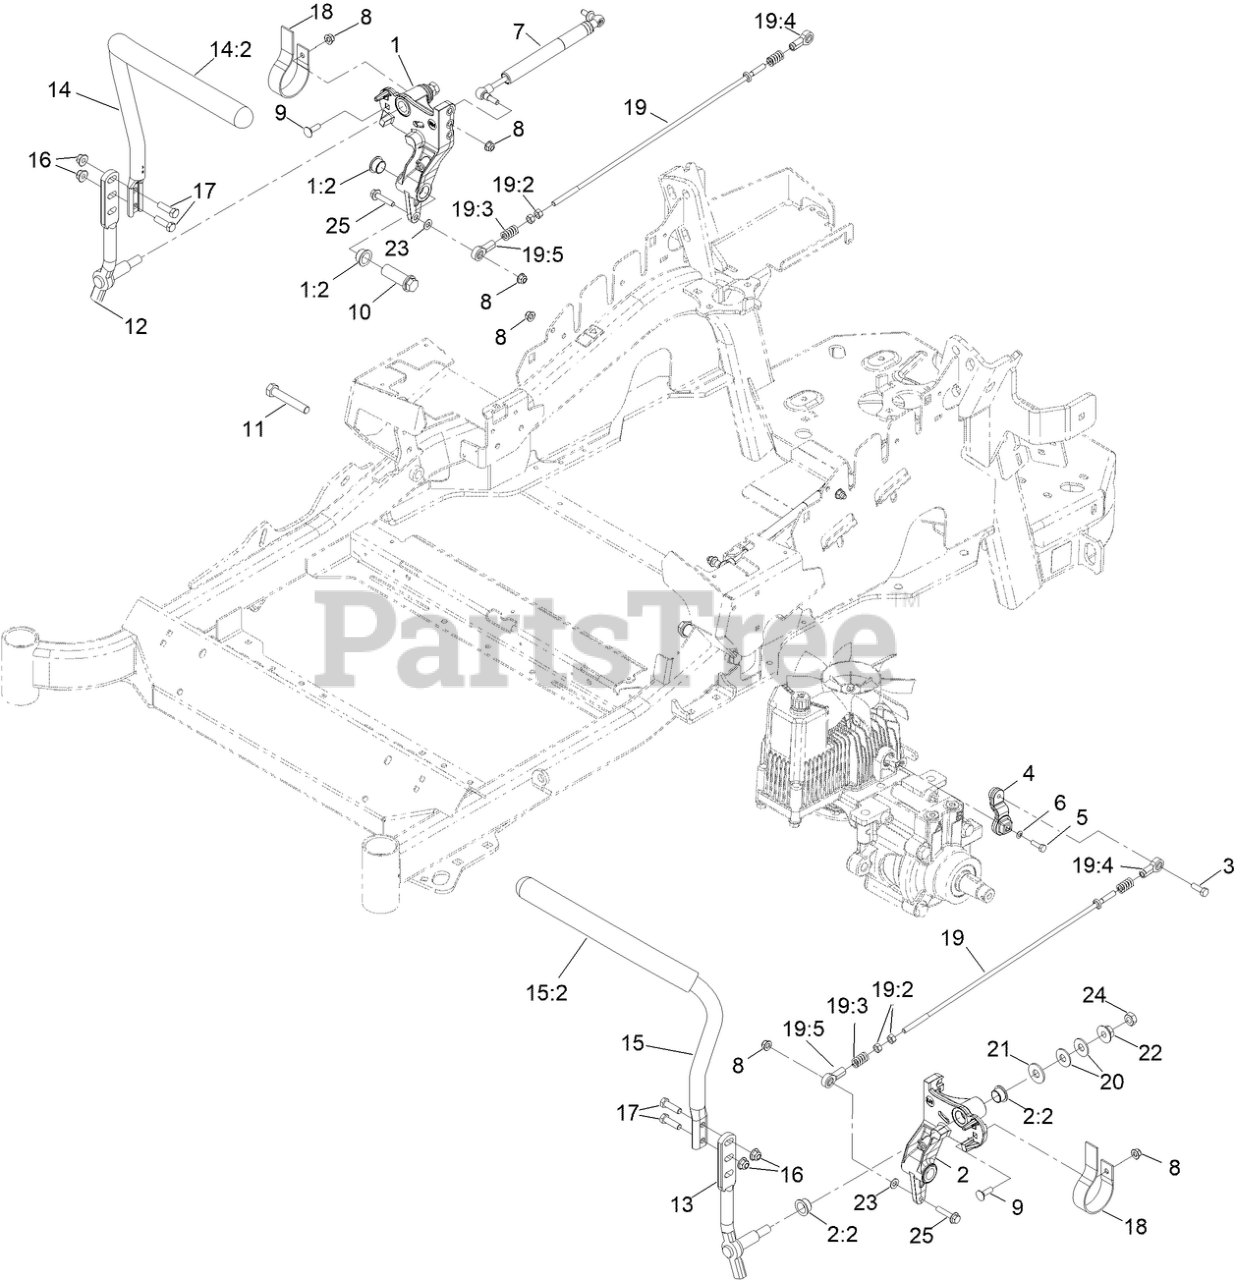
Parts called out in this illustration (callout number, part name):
1	RH MOTION CONTROL AND BUSHING ASM
1:2	BUSHING-FLANGE
2	LH MOTION CONTROL AND BUSHING ASM
2:2	BUSHING-FLANGE
3	SCREW-HH, THREAD LOCKING
4	ARM-CONTROL, PUMP
5	SCREW-HH
6	WASHER-SPRING
7	DAMPER, MOTION CONTROL
8	NUT-HF, NI
9	BOLT-CARR
10	HUB-THREADED
11	SCREW-HH
12	LEVER-CONTROL MOTION, RH
13	LEVER-CONTROL MOTION, LH
14	HANDLE- RH W/GRIP
14:2	GRIP-CONTROL, LEVER
15	ASM-HANDLE-LH
15:2	GRIP-CONTROL, LEVER
16	NUT-HF, NI
17	SCREW-HH
18	SPRING-LEAF
19	PUMP LINKAGE REAR ASM
19:2	NUT-HEX
19:3	SPRING-COMPRESSION
19:4	BALLJOINT-LH
19:5	BALLJOINT-RH
20	WASHER-SPRING
21	WASHER-FLAT
22	NUT-HF
23	WASHER-PLAIN
24	NUT-JAM
25	SCREW-HHF
